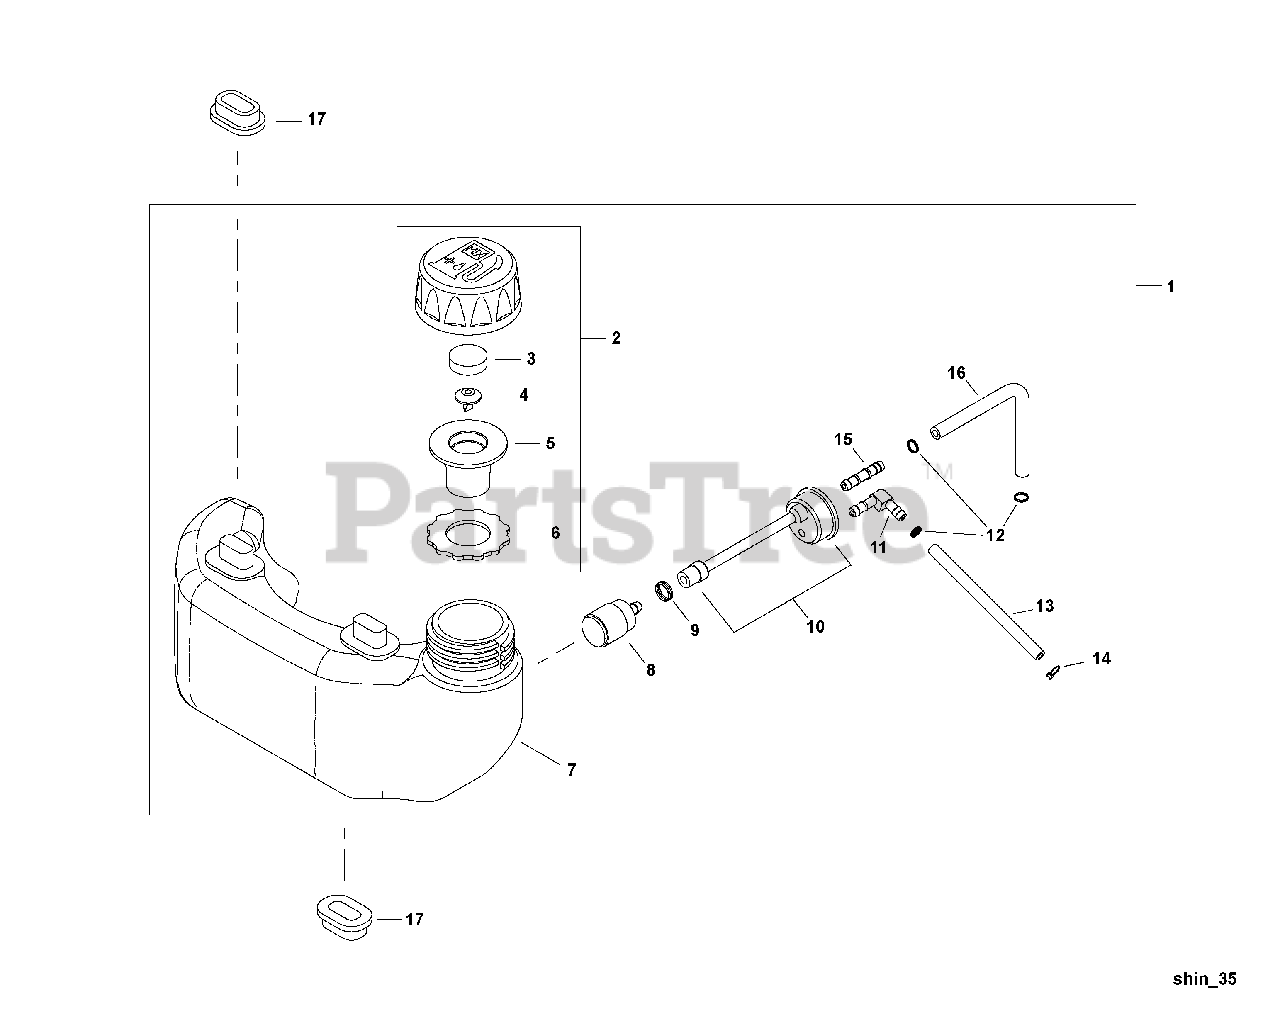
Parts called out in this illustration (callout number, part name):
1	TANK ASSY, FUEL
2	CAP, FUEL
3	PACKING, VENT
4	VENT ASSY
5	HOLDER, VENT
6	GASKET, FUEL CAP
7	TANK, FUEL
8	FILTER, FUEL 125-528
10	GROMMET, FUEL WITH PIPE
11	CONNECTOR, PIPE
12	CLIP Ø6
13	PIPE, FUEL RETURN
14	CLIP, SPRING Ø5.2
15	CONNECTOR, PIPE
16	PIPE, FUEL
17	CUSHION, FUEL TANK
